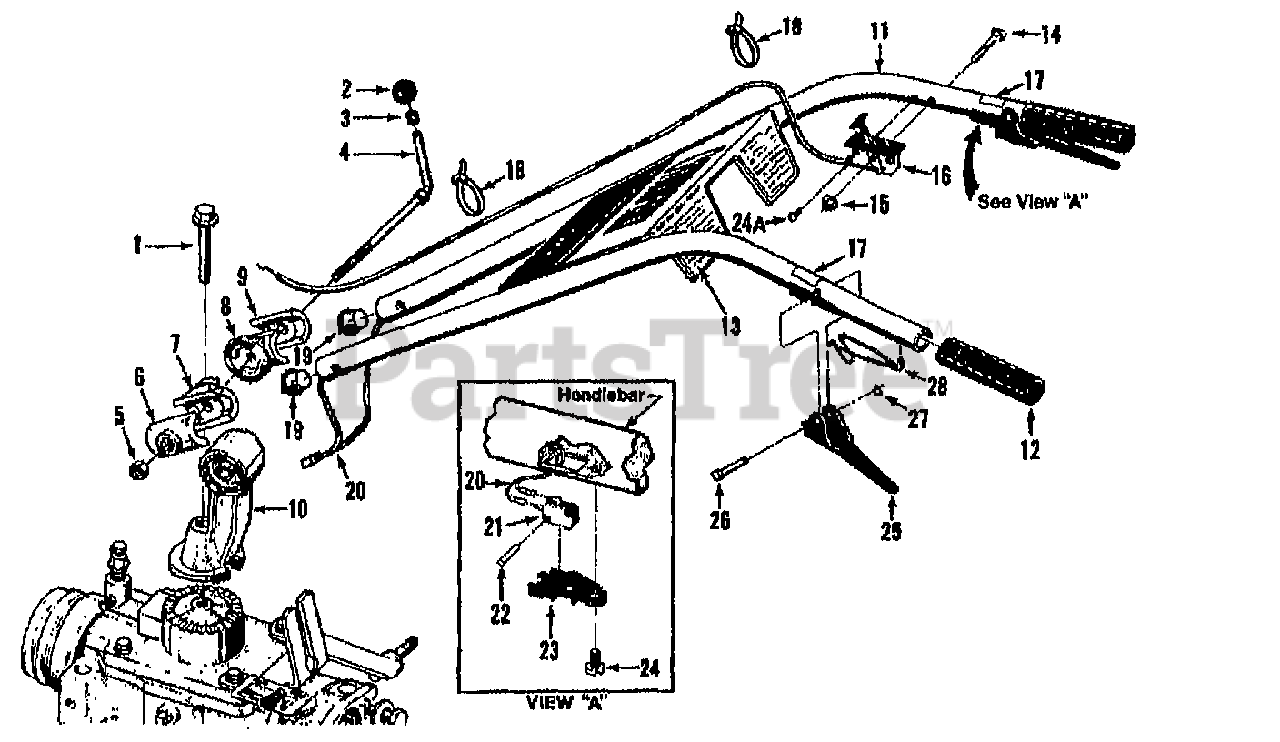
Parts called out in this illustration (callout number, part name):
1	BOLT 1/2-13X3.5 FH GR5
2	KNOB-CONTROL (INCL. 3)
3	RING-TOLERANCE .5325 ID
4	STUD-H/BAR W/NUT & RING (INCL. 2,3 & 5)
5	NUT-HEX JAM 1/2-13
6	CLAMP-LH HORSE 1021-1
7	RATCHET-H/BAR RED 2542-1
8	RATCHET-RH RED HORSE 2542-2
9	CLAMP-RH HORSE 1021-2
10	BASE-H/BAR RED 2534A
11	ASSM-HANDLEBAR W/GRIPS (INCL. 2 OF EA. 12, 17 & 28 AND ONE 13)
12	GRIP-H/BAR SMOOTH
13	DECAL-CONTROL PANEL HORSE
13	DECAL-CONTROL PANEL (11HP)
14	BOLT-CH 1/4-20X2.00 ZP
15	NUT-HF/LK 1/4-20 ZP
16	CABLE-THROTTLE 7 I/C B&S {12068/069/080/081/087}
16	CABLE-THROTTLE 7&8 B&S {12074/075/088/089/090}
16	CABLE-THROTTLE 8HP OPC {12070/071/082/083}
17	DECAL-FWD INTERLOCK
18	TIE-RED
19	RETAINER-HARNESS H/B OPC
20	HARNESS-WIRE OPC HORSE
21	SWITCH-H/B OPC
22	PIN-LK .11X.58 HORSE OPC
23	HOUSING-SWITCH OPC
24	SCR-HW M10-24X.5 STH ZP
24A	SCR-PHS M10-32X.5 STH ZP
25	LEVER-HORSE OPC
26	PIN-PIVOT OPC LEVER
27	RING-KLIP 5304-25
28	SPRING-H/B LEVER
